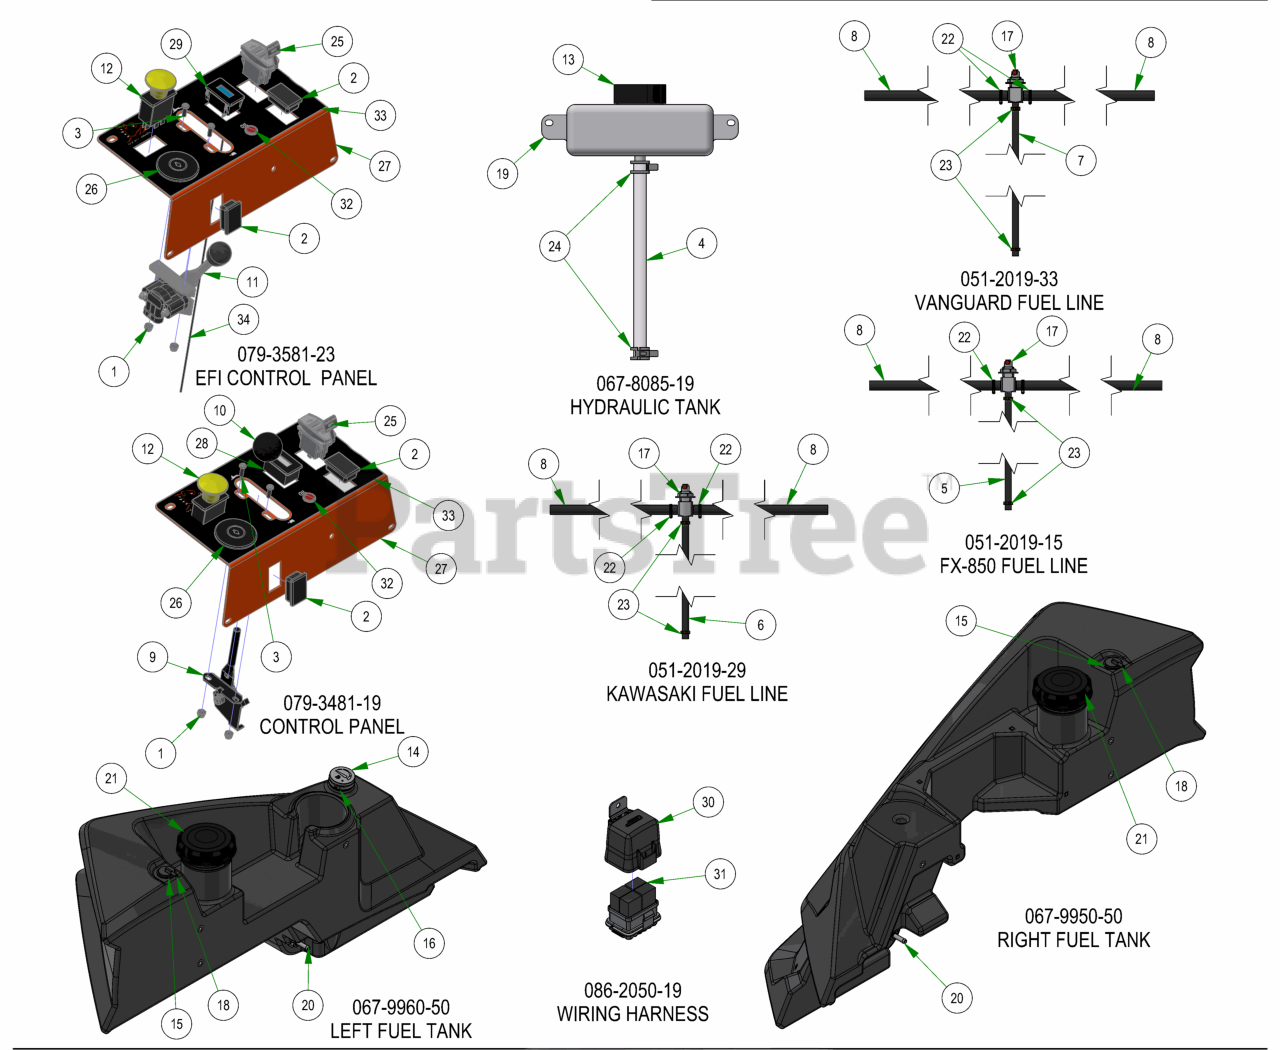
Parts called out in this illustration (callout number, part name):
1	10-24 NYLON INSERT LOCKNUT ZINC
2	Light Plug
3	10-24 X 5/8 BUTTON SOCKET CAP SCREW 18-8 STAINLESS STEEL
4	5/8 Braided Hose
5	1/4" Fuel Line Hose
6	1/4" Fuel Line Hose
7	1/4" Fuel Line Hose
8	5/16" fuel line hose
9	Universal Throttle Head - 2012
10	Throttle Knob
11	Kawasaki \ Kohler Drive By Wire
12	PTO Switch
13	Hydraulic Tank Cap
14	Fuel Gauge with Grommet
15	Roll Over Valve Grommet
16	Fuel Gauge Grommet
17	3 Way Fuel Shut-Off Valve 5/16 x 5/16 x 1/4
18	Rollover Valve
19	Expansion Tank Outlaw
20	Fuel Pick-up
22	5/16 Fuel Line Clamp
23	1/4 Fuel Hose Clamp
24	CTB-22 HOSE CLAMP
26	Ignition Switch
27	2022 Rebel Control Panel
28	Tachometer
29	Hour Meter EFI/EVO
30	Relay Block Cover Replacement Kit
33	2022 Rebel/Rogue Control Panel Decal
34	2023 REBEL/ROGUE Tach Ground Wire Assy
